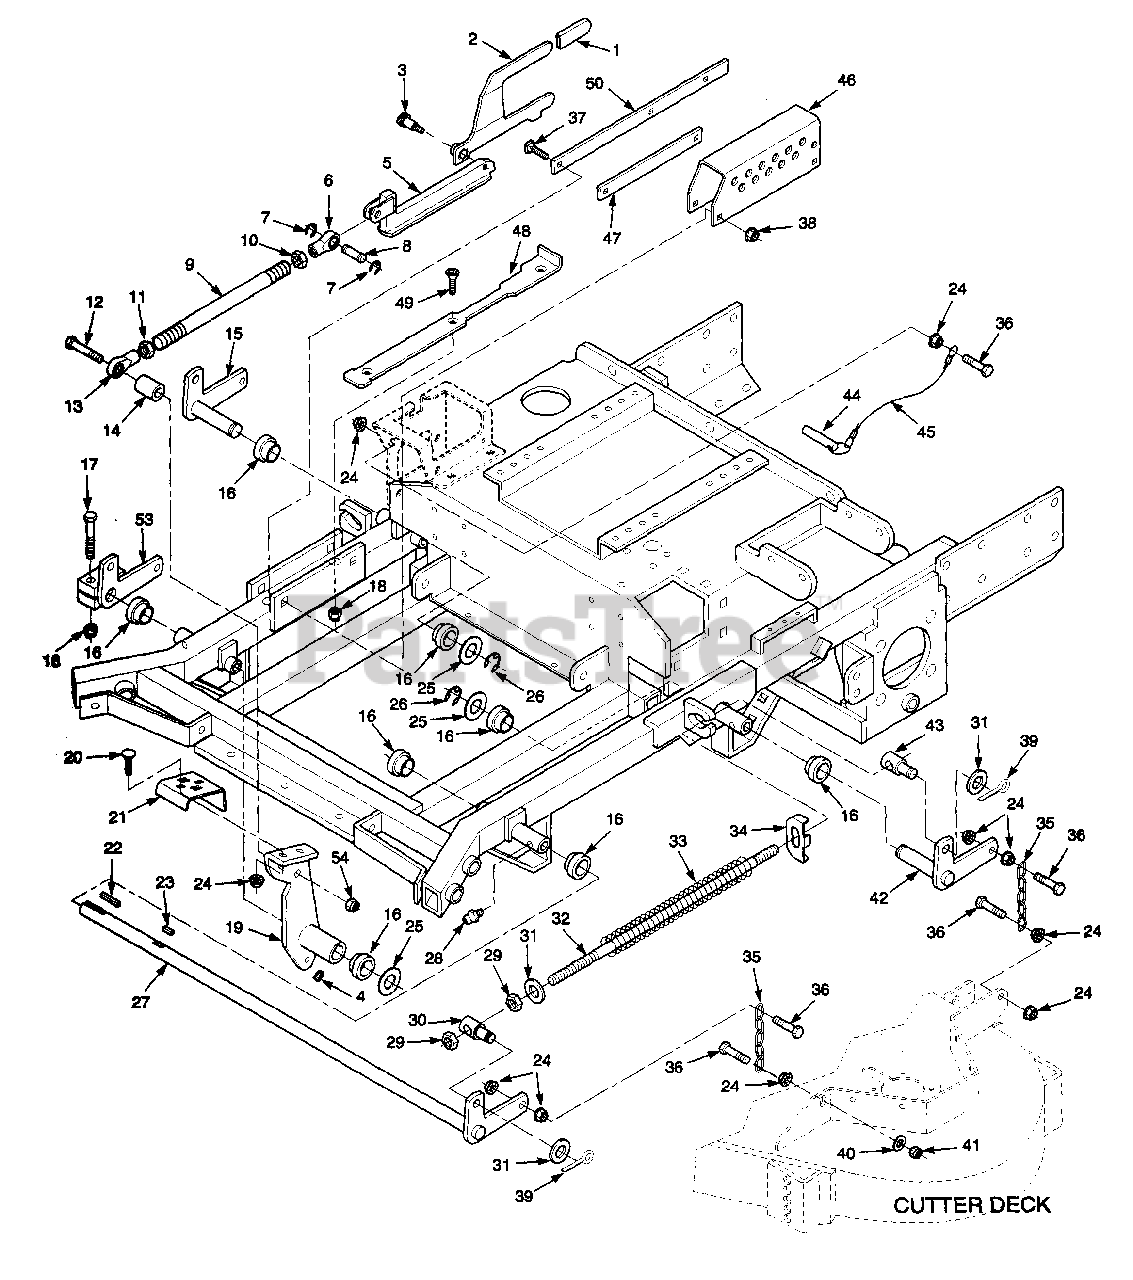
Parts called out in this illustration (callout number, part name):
1	Grip, Deck Latch
2	Deck Latch
3	Bolt, Shoulder 1/2 x 3/4"
4	Set Screw, 5/16-18 x 1/2" Sq. Head
5	Lockplate, Decklift
6	Rod End, Female - 1/2-20 LH
7	Ring, Retaining 1/2" External "E"
8	Pin, Decklift
9	Link, Decklift
10	Nut, Jam 1/2-20 LH
11	Nut, Jam 1/2-20 RH
12	Bolt, Hex Head 1/2-13 x 3"
13	Rod End, Female - 1/2-20 RH
14	Spacer, Decklift Pedal
15	Bellcrank Weldment, RH Rear
16	Bushing, 1.003 ID.
17	Bolt, Hex Head 7/16-14 x 2.5"
18	Nut, Hex Elastic Stop 7/16-14
19	Footplate Weldment, Decklift
20	Bolt, Carriage 5/16-18 x 1"
21	Footplate, Height Adjustment
22	Key, 1/4 x 1/4 x 1-1/4"
23	Key, 1/4 x 1/4 x 3-1/4"
24	Nut, 3/8-16 Hex, Serrated Flange
25	Flatwasher, 1" (1.062 x 1.50 x .048)
26	Ring, Retaining 1" External "E"
27	Bellcrank Weldment, LH Front
28	Grease Fitting
29	Nut, Hex 5/8-11
30	Swivel Joint, RH
31	Flatwasher, 5/8" (.656 x 1.312 x .095)
32	Stud, 5/8-11 x 22.0"
33	Spring, Deck Lift
34	Flatwasher, Spring Stop
35	Chain
36	Bolt, Hex Head 3/8-16 x 1-1/2"
37	Flatwasher, 5/8" (.656 x 1.312 x .095)
38	Nut, Hex 5/8-11
39	Pin, Cotter 3/16 x 1.0"
40	Flatwasher, 3/8"
41	Nut, 3/8-16 Elastic Stop
42	Bellcrank Weldment, LH Rear
43	Swivel Joint, LH
44	Ring Pin, 1/2 x 3.30"
45	Lanyard, Deck Height Pin
46	Bracket, Cutting Height Adjustment
47	Guide, Short
48	Lockplate, Decklift
49	Screw, Cap 5/16-18 x 3" FHHS
50	Guide, Long
